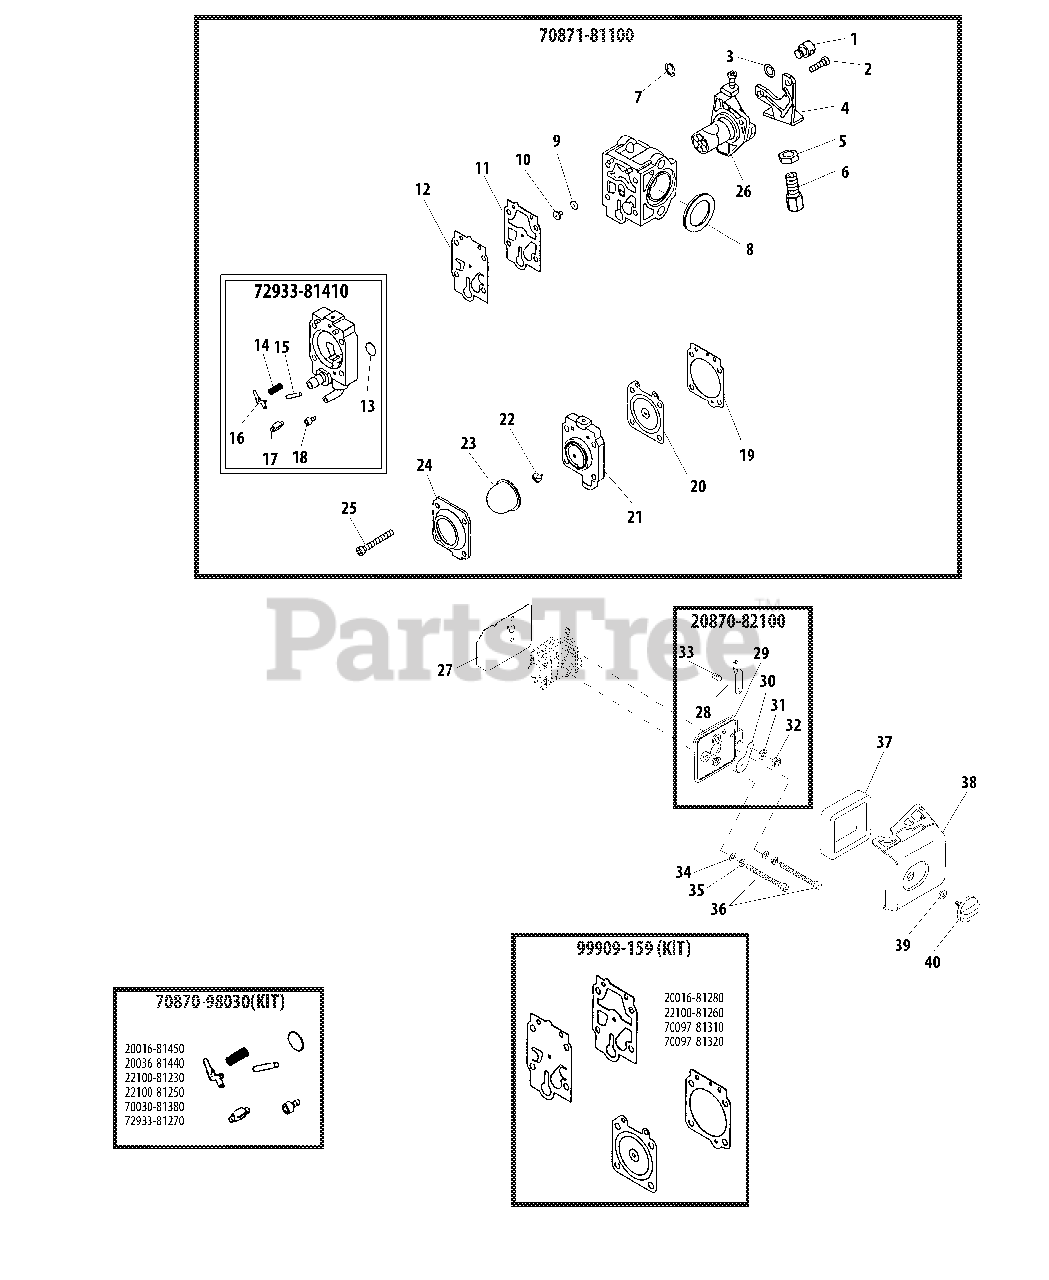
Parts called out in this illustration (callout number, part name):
1	SWIVEL
2	SCREW
3	WASHER
4	BRACKET, CABLE
5	NUT
6	NUT, CABLE ADJUST
7	RING, RETAINING
8	SEAL
9	O-RING
10	JET
11	GASKET, PUMP
12	DIAPHRAGM, PUMP
13	STRAINER
14	SPRING, METERING LEVER
15	PIN, METERING LEVER
16	LEVER, METERING
17	VALVE, INLET NEEDLE
18	SCREW, METERING LEVER PIN
19	GASKET, METERING
20	DIAPHRAGM, METERING
21	BASE, PURGE
22	VALVE, CHECK
23	BULB, PURGE
24	RETAINER, PURGE BULB
25	SCREW, PUMP COVER
26	THROTTLE VALVE ASSY
27	GASKET
28	LEVER, CHOKE
29	CASE, AIR FILTER
30	PLATE, CHOKE
31	LOCKWASHER - 6
32	NUT - 6
33	SHAFT, CHOKE
34	WASHER - 5
35	LOCKWASHER - 5
36	SCREW - 5X60
37	FILTER, AIR
38	COVER, AIR FILTER
39	WASHER - VINYL
40	THUMBSCREW
20870-82100	AIR FILTER CASE ASSY
70870-98030	REPAIR KIT
70871-81100	CARBURETOR
72933-81410	BASE, PURGE
99909-159	DIAPHRAGM/GASKET KIT
